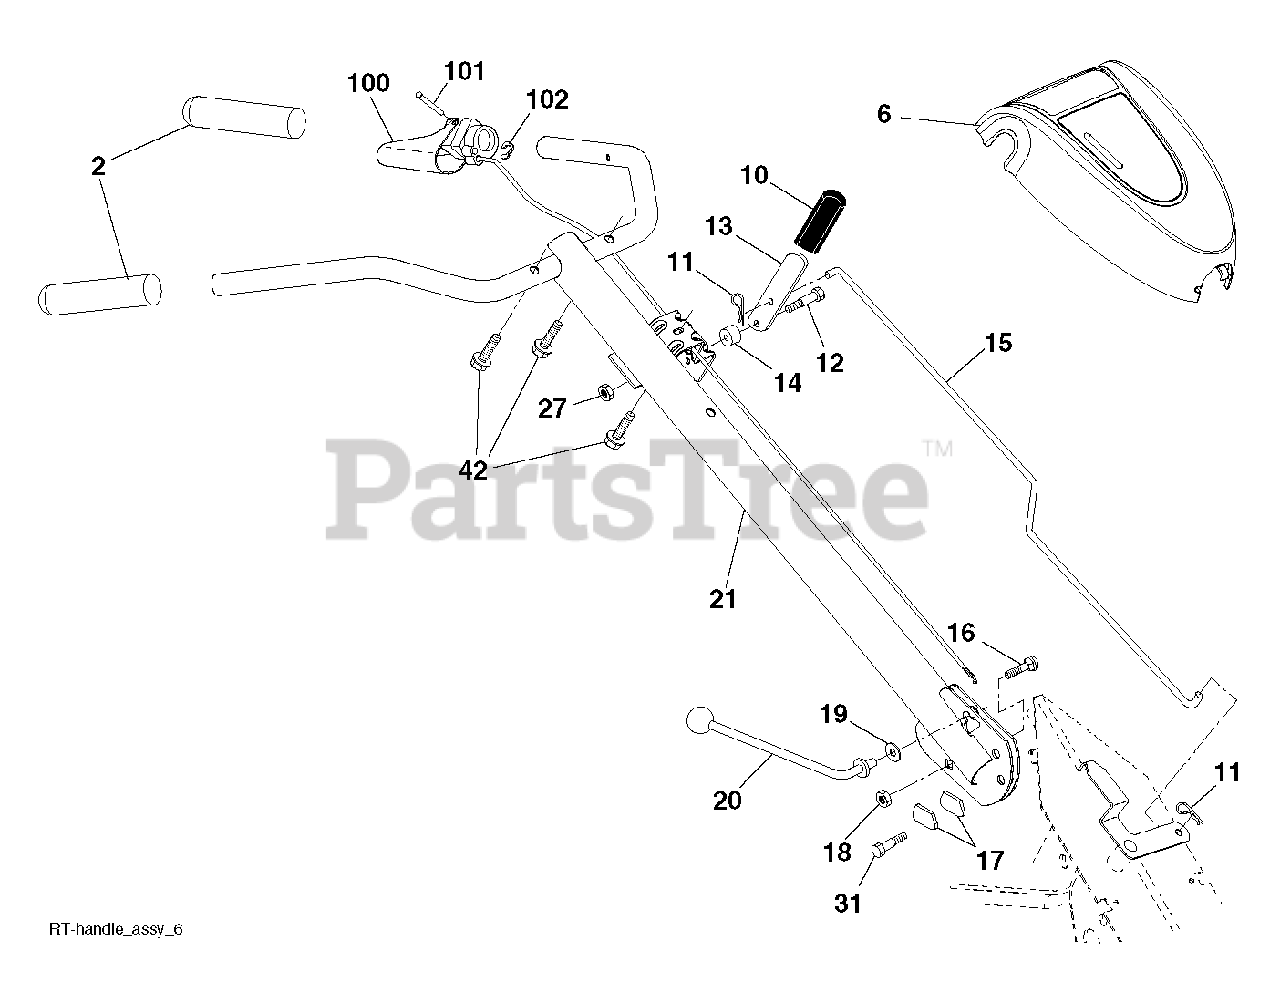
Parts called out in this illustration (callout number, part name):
2	GRIP.1X5.06
10	GRIP T
11	RETAINER M
12	SHOULDER BOLT ST
14	GROMMET.RUBBER.CRT.TILLER
15	ROD, SHIFT
18	LOCKNUT
19	WASHER CRT
20	LEVER.LOCK.CRT
21	Curved Plow Handle Assembly for Tiller, Black
27	NUT T
31	BOLT.PIVOT
42	SCREW.#10 X 0.750.BOS THREAD
100	CONTROL.ASSEMBLY.TINE.TILLER
101	PIN, PIVOT
102	RETAINING RING
